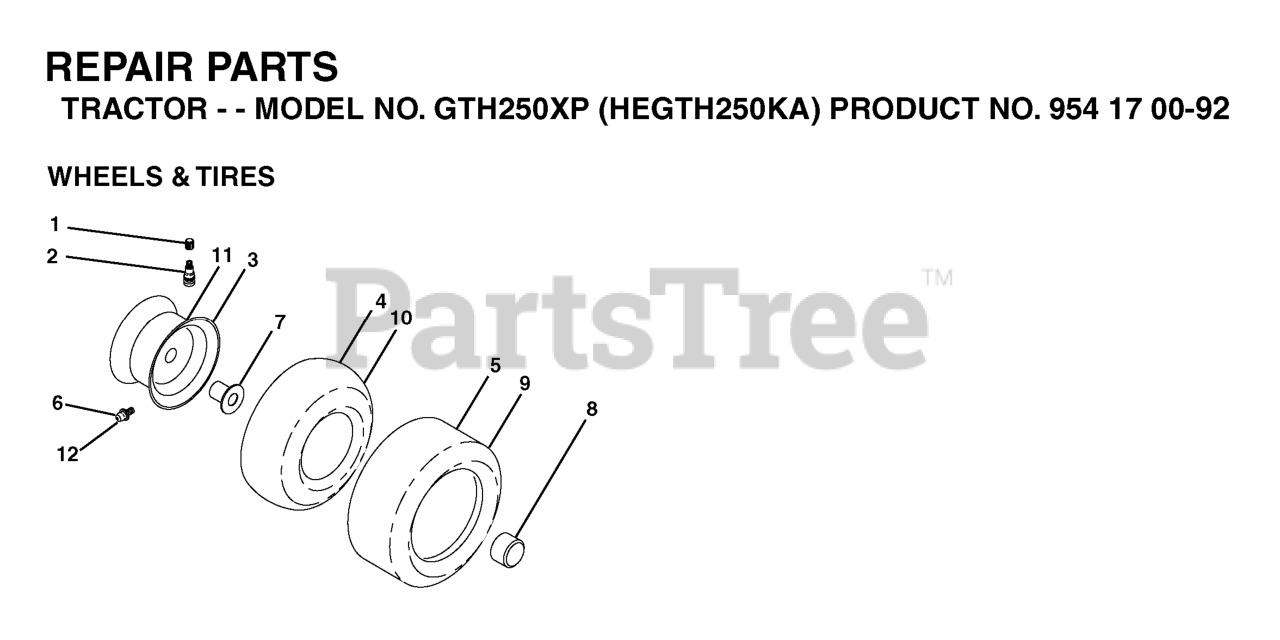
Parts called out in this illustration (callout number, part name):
2	VALVE STEM LT
3	RIM ASSEMBLY, FRONT
4	TUBE.16X6.5/7.5-8
5	TIRE HEAVY DUTY
6	FITTING LT
7	BEARING T
8	CAP, AXLE BLK
9	TIRE HEAVY DUTY
10	TUBE.23X9.5-12
11	RIM.ASM.12X7.REAR.SILVER
12	ZERK FITTING M
